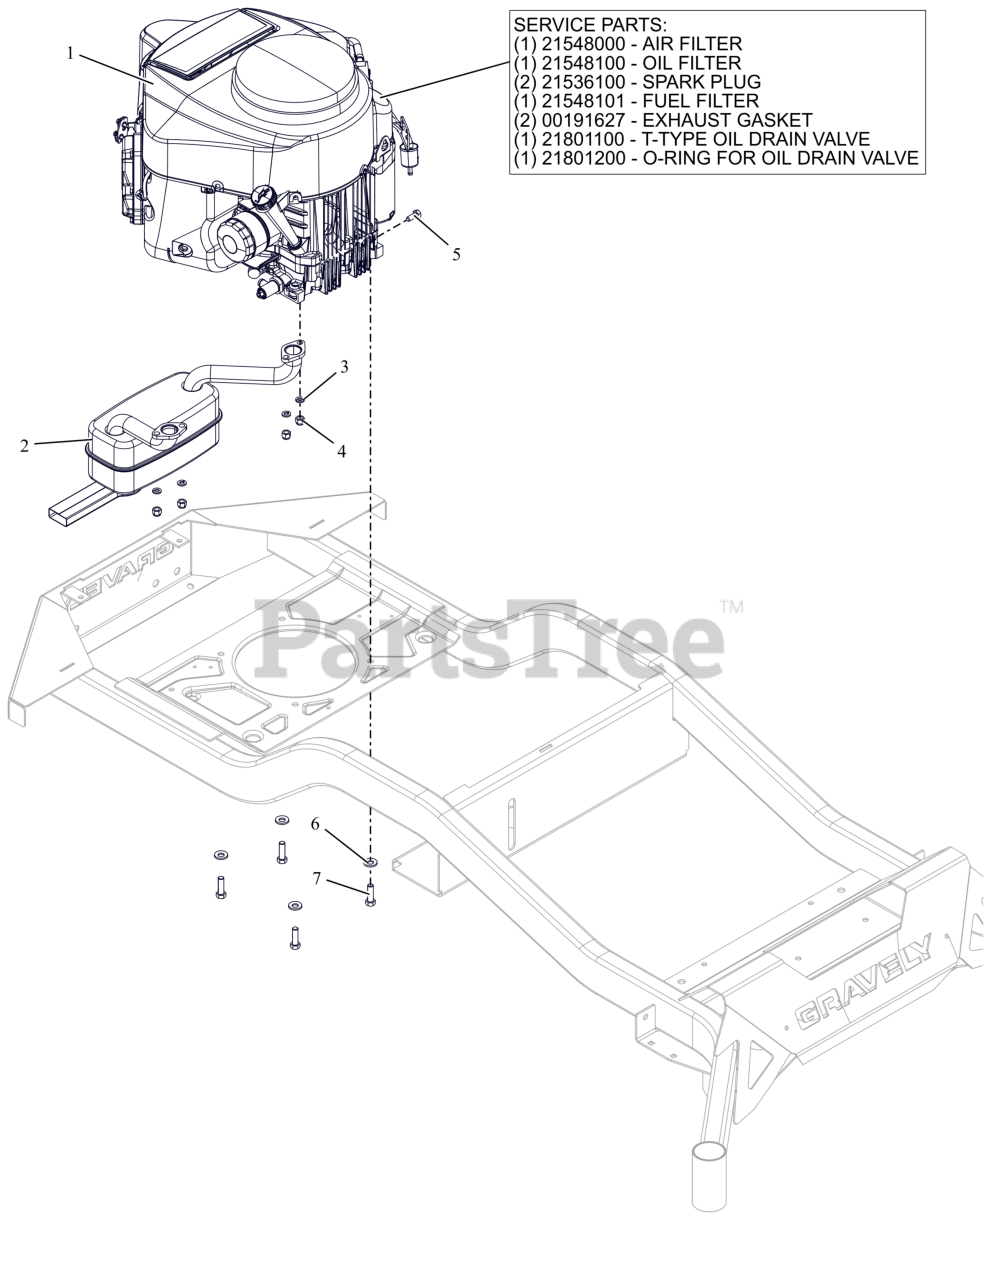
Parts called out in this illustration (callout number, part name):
1	ENGINE, KAWASAKI FR730 24HP
1	AIR FILTER, KAWASAKI FR
1	OIL FILTER, KAWASAKI FR
1	PLUG, SPARK
1	FUEL FILTER-KAWASAKI FR
1	GASKET, MUFFLER S/O
1	VALVE- T-TYPE OIL DRAIN
1	O-RING- OIL DRAIN VALVE
2	MUFFLER, KAWASAKI
3	WSHR,LK-REG .312X.078 ZCC
4	NUT,NYL M8-1.25 G8.8 ZCC
5	BLT, HEX M8-1.25X20 G8.8 ZCC
6	WASHER, 3/8" SPRING DISC
7	BLT, HEX .38-16X1.25 G5 ZCC NT
